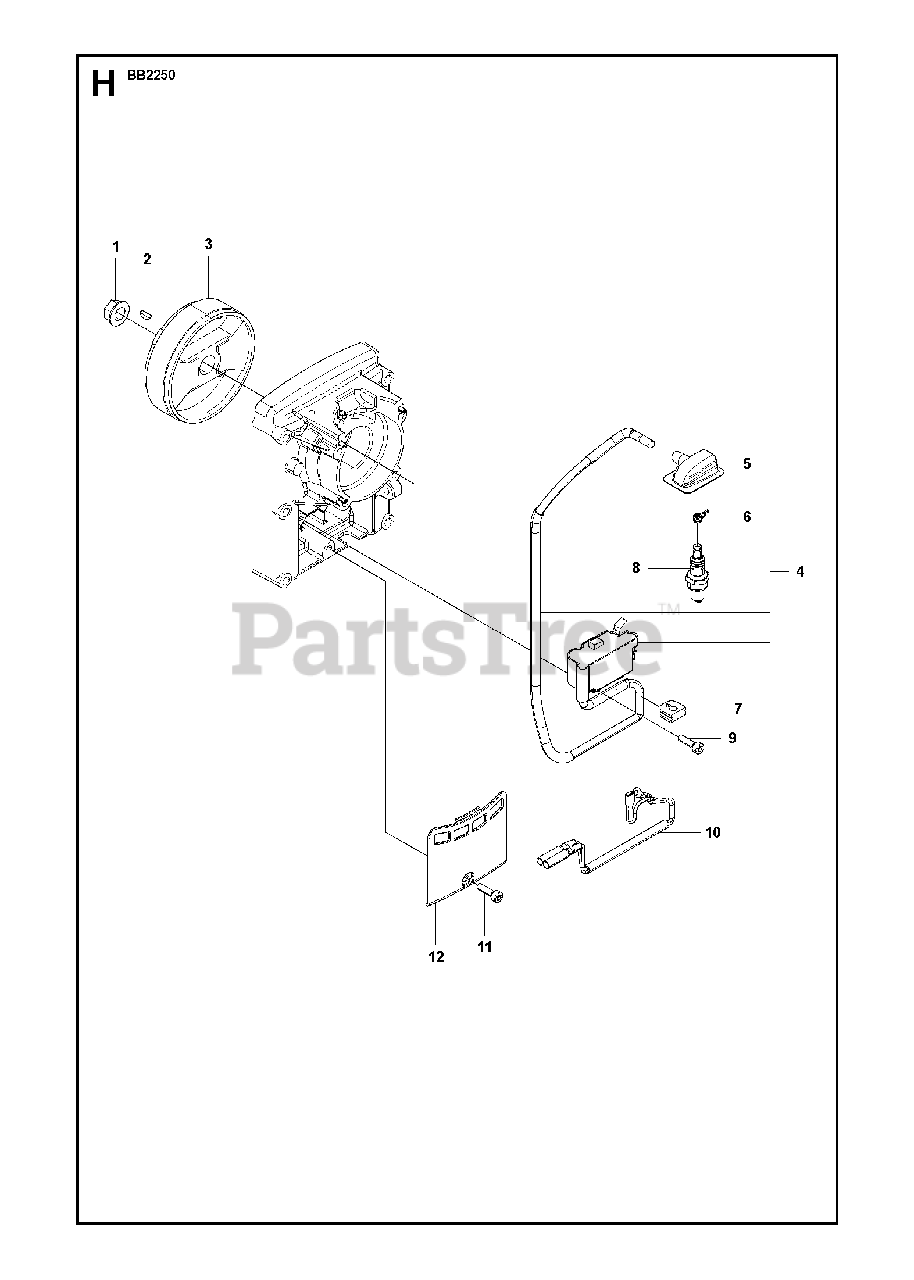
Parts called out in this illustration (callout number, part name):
1	NUT
2	KEY
3	FLYWHEEL
7	GROMMET
8	SPARK PLUG NGK CMR7H
9	BOLT
10	CORD-C
11	BOLT
